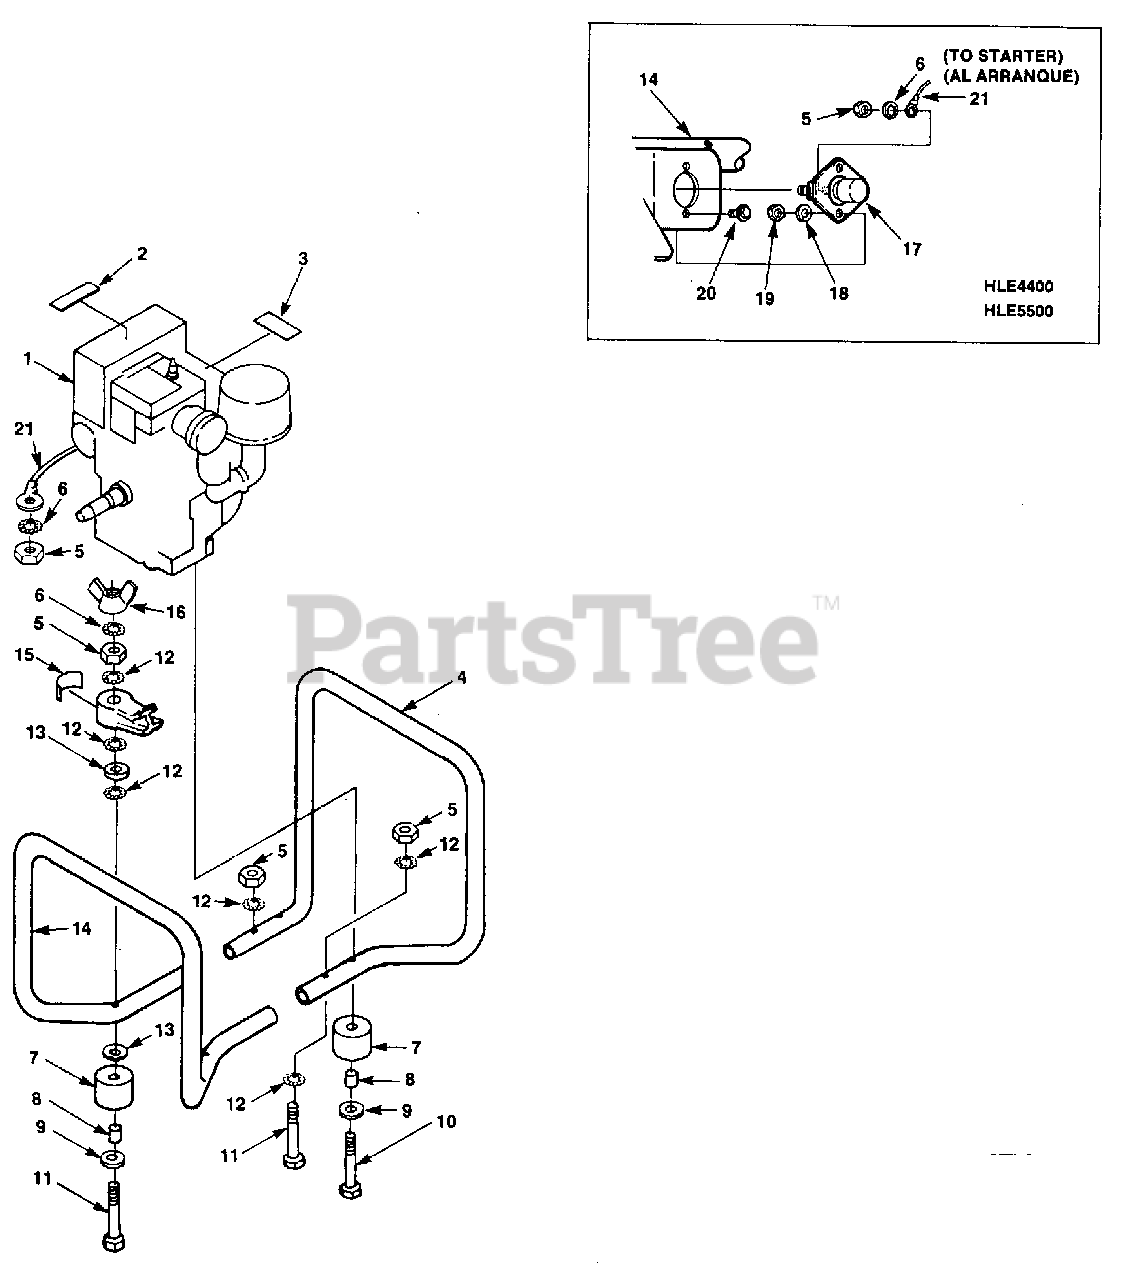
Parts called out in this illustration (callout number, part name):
1	ENGINE
2	DECAL- Warning
3	DECAL- Caution
4	MEMBER- Frame (Engine)
5	NUT- Hex (5/16-18)
6	WASHER- Locking (5/16")
8	SPACER- Foot
9	WASHER- Flat (5/16")
10	SCREW- Cap hex hd (Gen & Carburetor Side)
11	BOLT- Engine (Rear)
12	WASHER- Lock ext./int.
13	WASHER- Flat (5/16")
14	MEMBER & STARTER BRACKET
15	DECAL- Ground
16	NUT- Wing- (5/16-18)
17	SWITCH- Starter
20	SCREW- Hex hd
